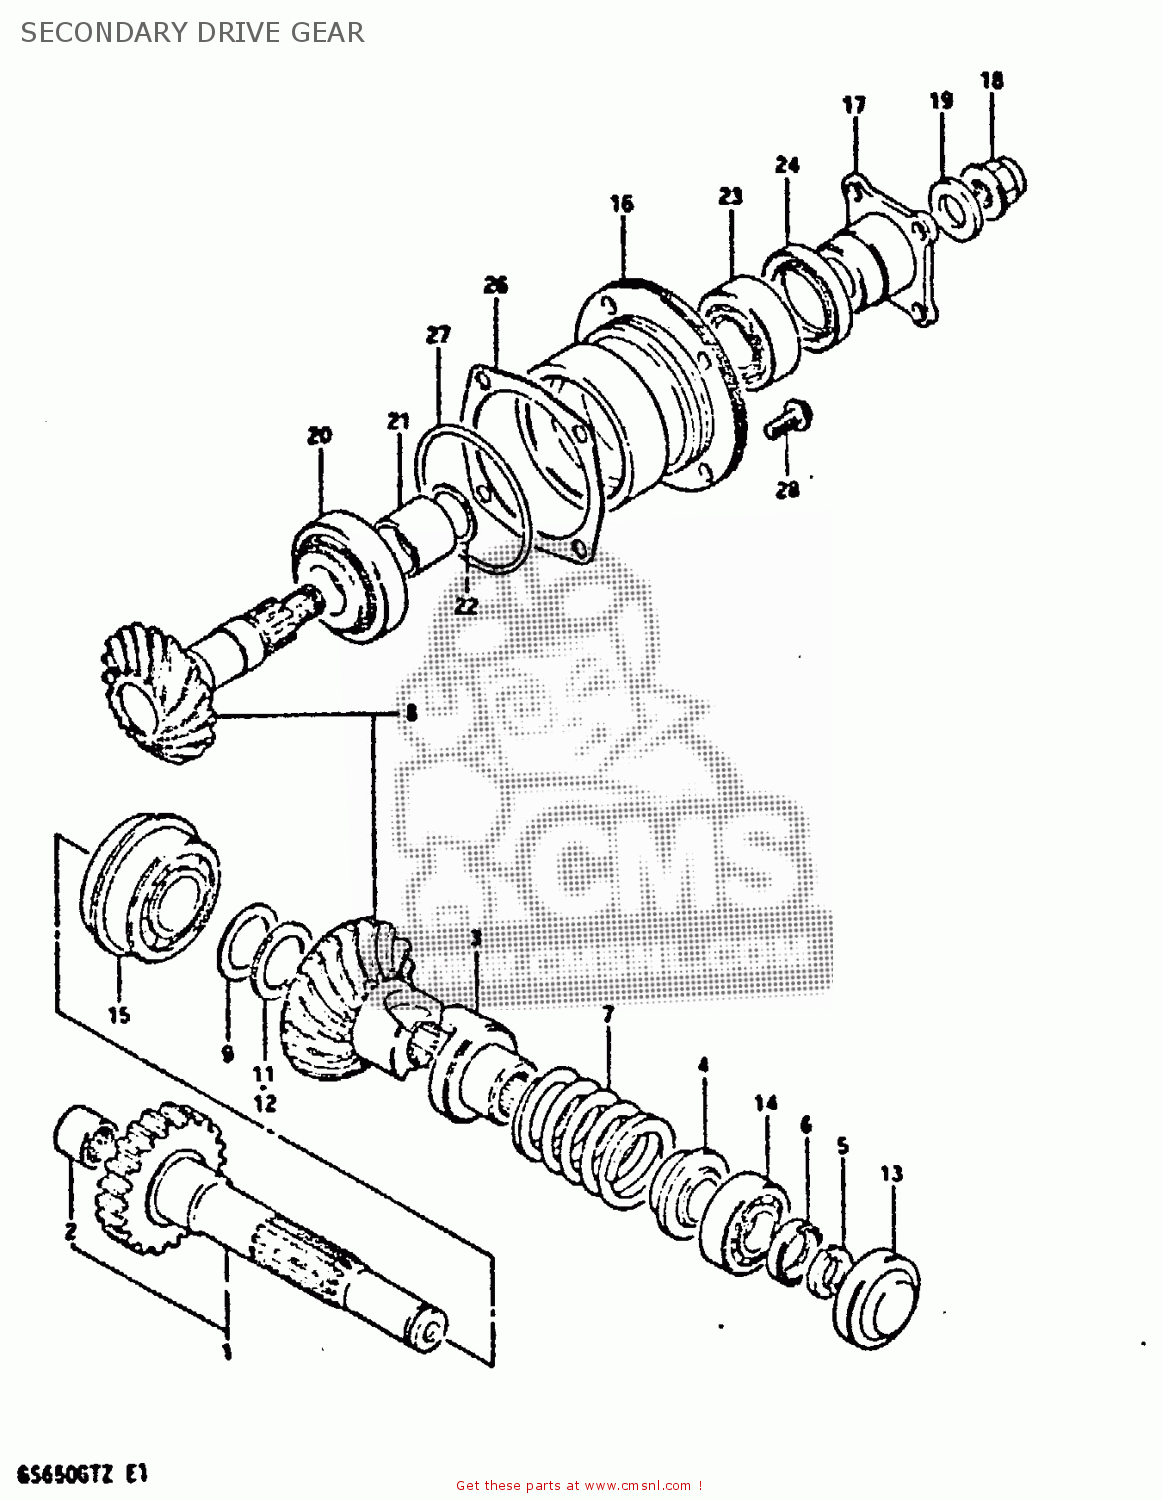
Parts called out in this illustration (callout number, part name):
1	SHAFT,OUTPUT
2	BEARING(15X23X20)
3	DOG
4	STOPPER
5	STOPPER,CAM DOG
6	HOLDER,CAM DOG STOPPER
7	SPRING
8	SECONDARY GEAR SET
9	SHIM,SECONDARY DRIVE
11	SHIM,SECONDARY DRIVE BEVEL
12	SHIM,SECONDARY DRIVE BEVEL
13	PLUG
14	BEARING(20X47X14)
15	BALL BEARING 30X62X24
16	HOUSING,SECONDARY DRIVE
17	FLANGE,UNIVERSAL JOINT
18	NUT
19	WASHER(14X29X4)
20	TAPER,ROLLER BEARING
21	SPACER (25.2X30X40)
22	SHIM (25X30X2
23	BEARING
24	SEAL,OIL(35X52X9)
26	SHIM,DRIVEN GEAR HOUSING
27	O RING(D:3.1,ID:69.4)
28	BOLT
